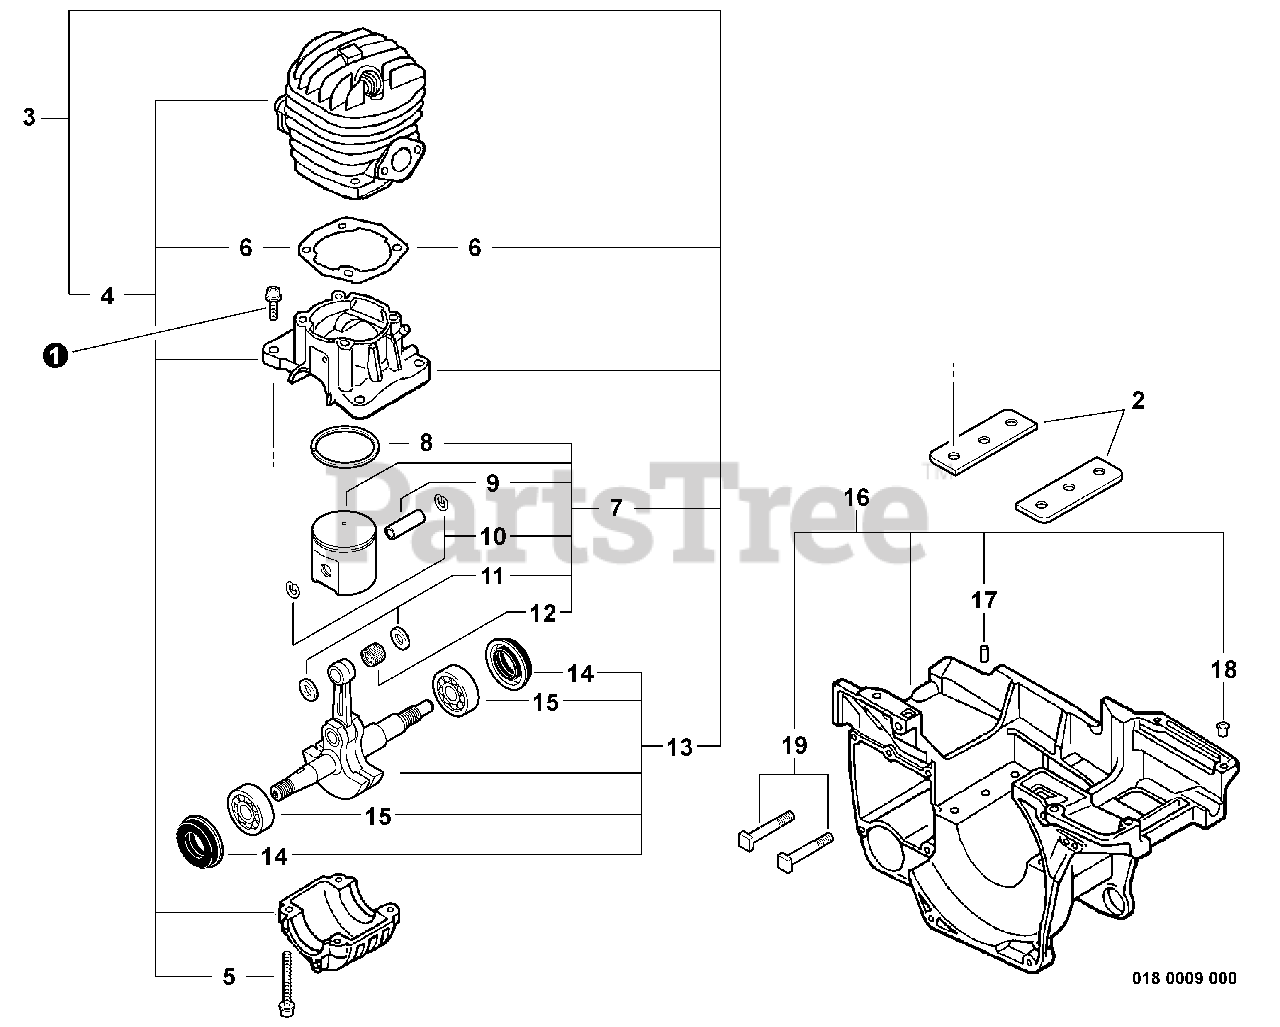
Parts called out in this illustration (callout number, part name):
1	SCREW - 5X22
3	SHORT BLOCK -- SB1094
4	CRANKCASE KIT
5	SCREW - 5X55
6	GASKET, CYLINDER
7	PISTON KIT
8	RING, PISTON
9	PIN, PISTON
10	RING, RETAINING
11	SPACER, PISTON
12	BEARING, NEEDLE
13	CRANKSHAFT ASSY
14	SEAL, OIL - 12
15	BEARING, BALL - 6201
16	ENGINE COVER ASSY
17	PIN - LOCATING
19	STUD, GUIDE BAR
